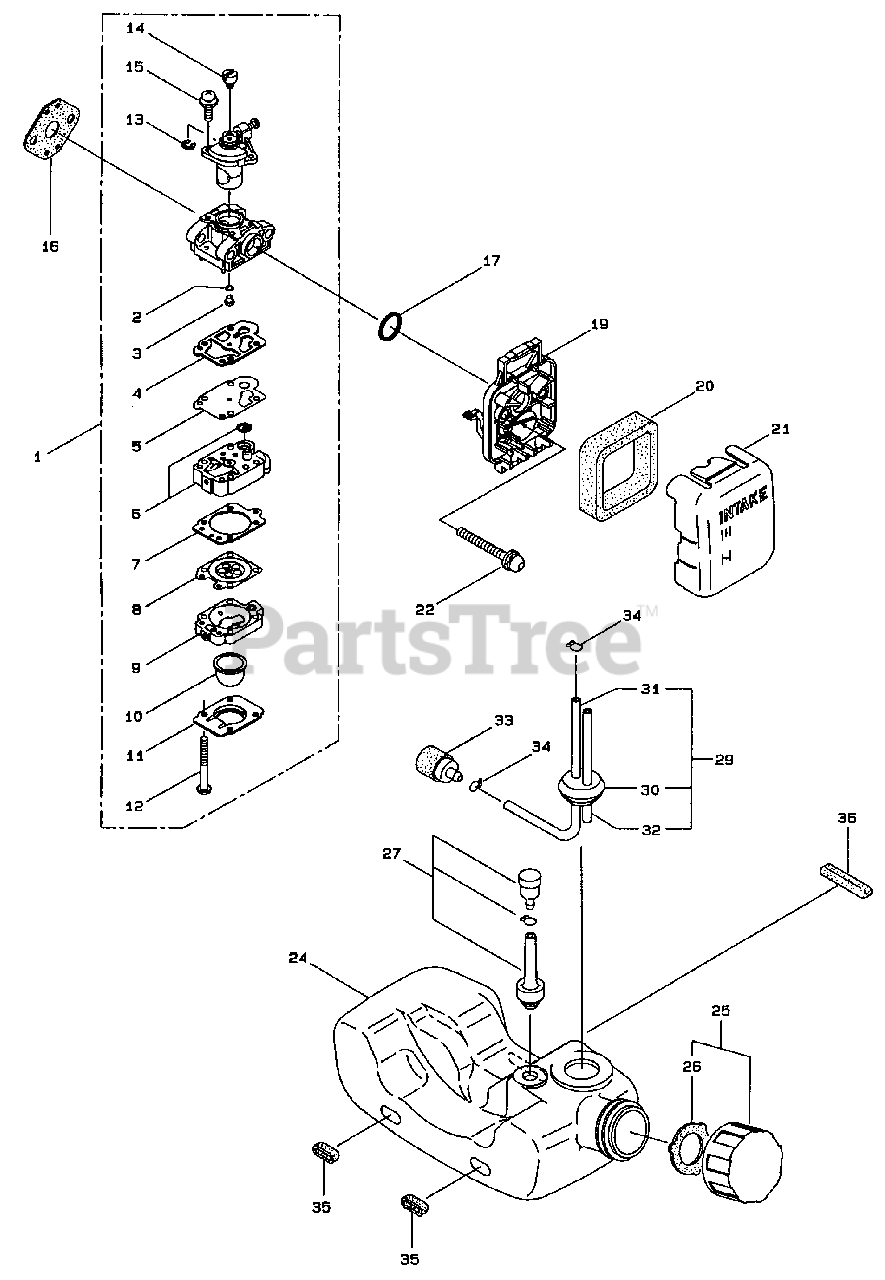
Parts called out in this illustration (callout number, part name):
1	Carburetor Assembly (Incl. Ref. #2-15)
3	Main Jet
5	Diaphragm-Fuel Pump
6	Body-Pump
8	Diaphragm-Metering
9	Body-Purge
10	Bulb-Primer
11	Plate-Cover
22	Cap Screw
24	Fuel Tank
25	Fuel Tank Cap Assembly (Incl. Ref. # 26)
27	Breather Assembly
29	Fuel Pipe Assembly (Incl. Ref. # 30-32)
31	Fuel Pipe
32	Return Pipe
33	Fuel Filter Assembly
